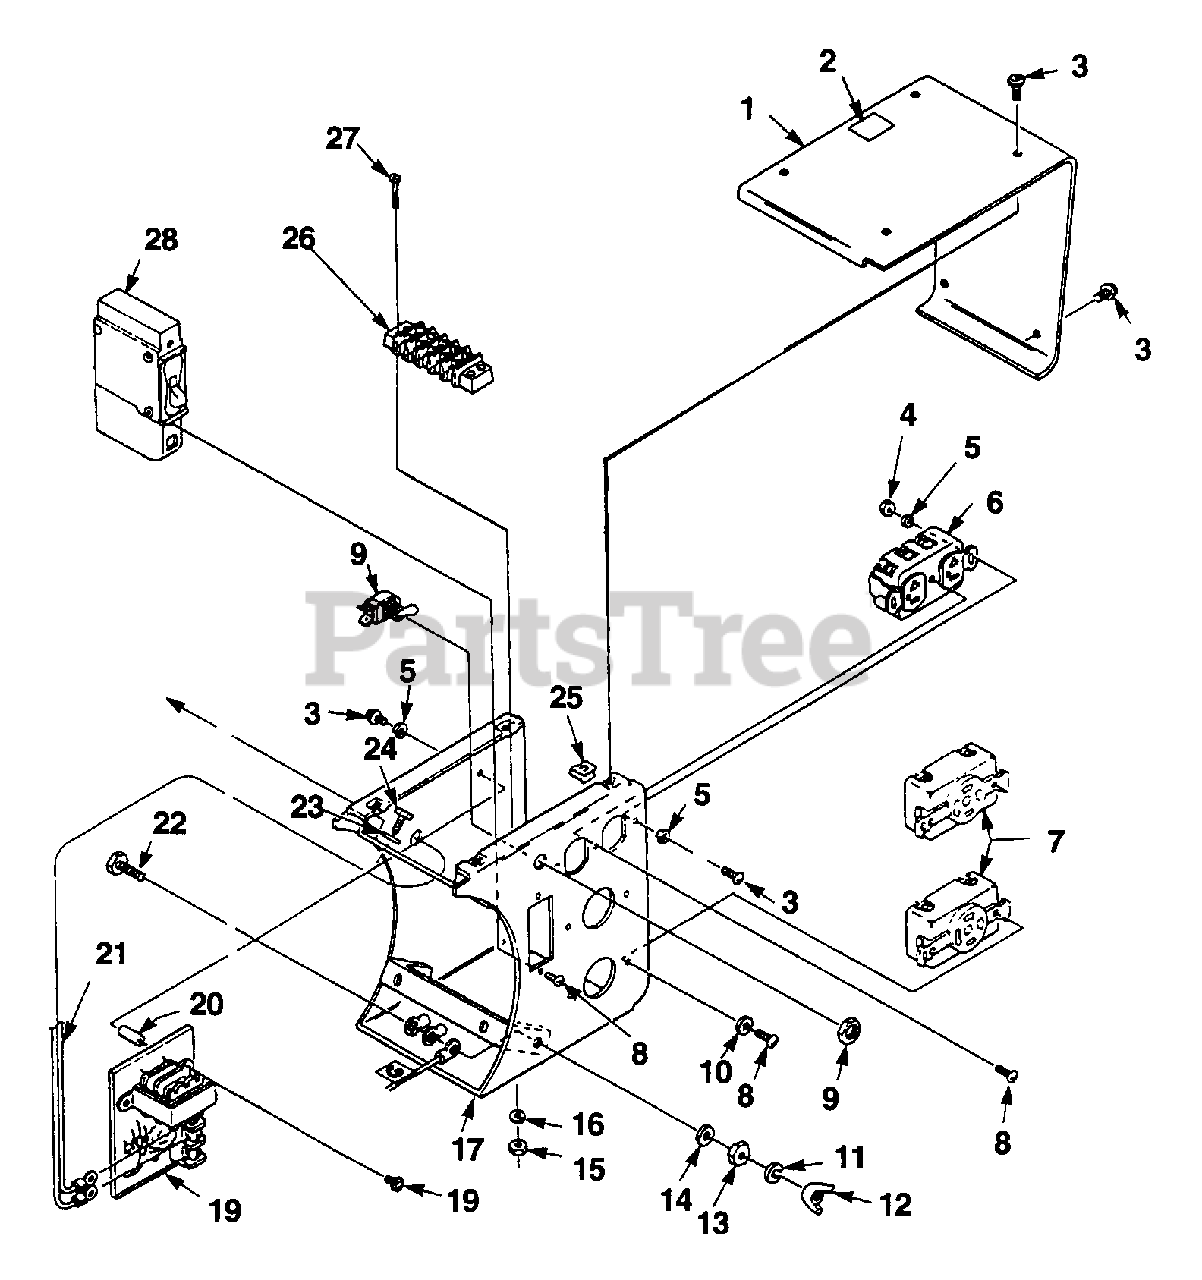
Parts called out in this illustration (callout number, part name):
1	COVER - Control Box
2	DECAL - Warning
3	SCREW - Mach Slot (8-32 X 3/8")
4	NUT - Hex (8-32)
5	WASHER - Lock (#8)
6	RECEPTACLE - Duplex (Nema 5-20R)
7	RECEPTACLE (3 Pole, 4 Wire)
8	SCREW - Round Hd (8-32 X 3/8")
9	SWITCH - Toggle (SPST)
10	WASHER - Lock (#6)
11	WASHER - Lock (5/16)
12	NUT - Wing (5-16-18)
13	NUT - Hex (5/16-18)
14	WASHER-Lock (5/16)
15	NUT - Hex (10-24)
16	WASHER - Lock (#10)
17	CONTROL BOX
19	SCREW - Mach Fil Hd (8-32 X 1/2")
21	ELECTROMAGNET
22	SCREW - Cap Hex Hd (5/16-18 X 1-1/4")
23	WASHER - Lock (1/4)
24	SCREW - Machine Hex Hd. (1/4-20 X 1/2")
25	NUT - Speed (8-32)
26	BLOCK - Terminal
27	SCREW - Machine (10-24 X 5/8")
28	BREAKER - Circuit (25A, 240V)
